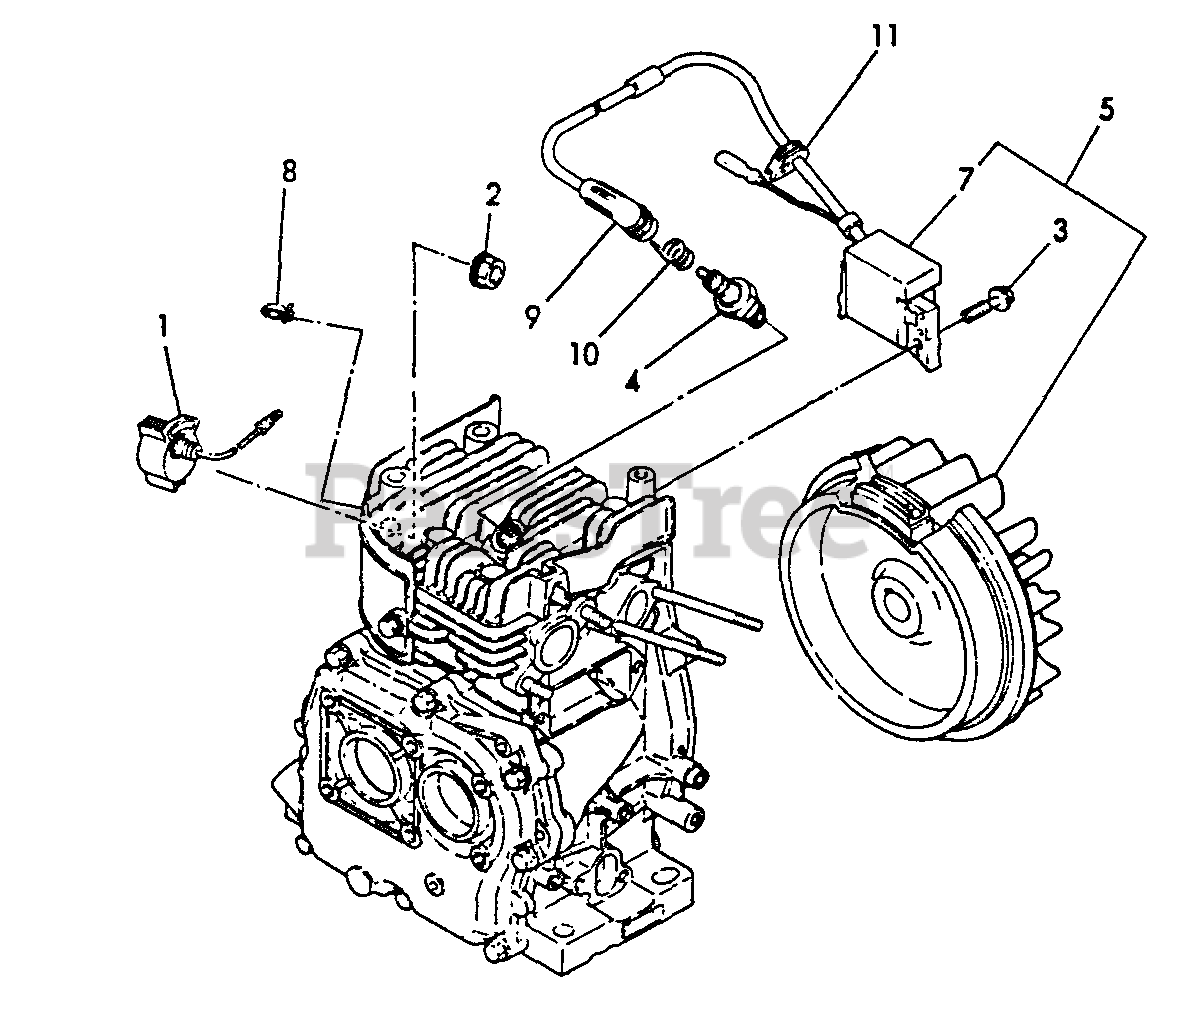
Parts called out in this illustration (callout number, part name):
1	IGNITION SWITCH ASSY
2	NUT - 8
3	BOLT - 6X25
4	SPARK PLUG
5	FLYWHEEL
7	COIL, IGNITION
8	CLAMP
9	CAP, PLUG
10	TERMINAL, SPARK PLUG CAP
11	GROMMET
